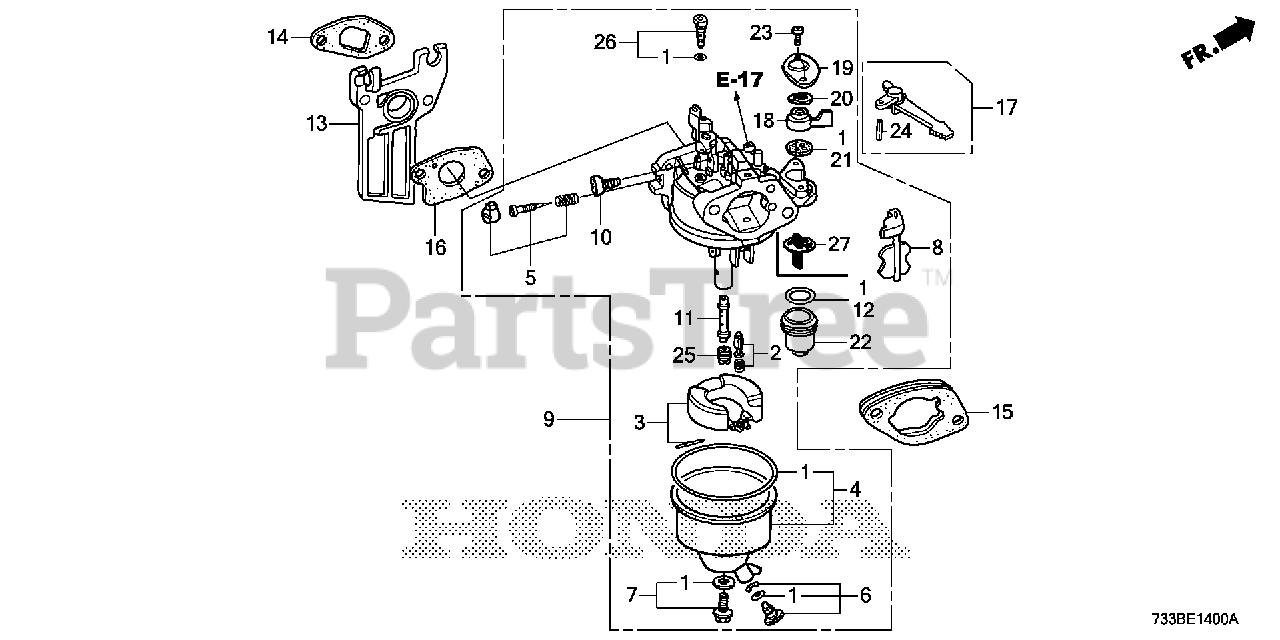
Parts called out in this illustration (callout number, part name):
1	GASKET SET
2	VALVE SET, FLOAT (SEAT NOT INCLUDED)
4	CHAMBER SET, FLOAT
5	SCREW SET, PILOT
6	SCREW SET, DRAIN
7	SCREW SET
9	CARBURETOR ASSY. (BE65F B)
10	SCREW, THROTTLE STOP
11	NOZZLE, MAIN
12	GASKET, FUEL STRAINER CUP
13	INSULATOR, CARBURETOR
14	GASKET, INSULATOR
15	SPACER, CARBURETOR
16	GASKET, CARBURETOR
17	LEVER, CHOKE (STD)
18	LEVER, PETCOCK
19	PLATE, LEVER SETTING
20	SPRING, PETCOCK LEVER
21	GASKET, PETCOCK
22	CUP, FUEL STRAINER
23	SCREW, PAN (3X6)
24	PIN, SPRING (2X12)
25	JET, MAIN (#65)
25	JET, MAIN (#68)
25	JET, MAIN (#70)
26	JET SET, PILOT (#38)
